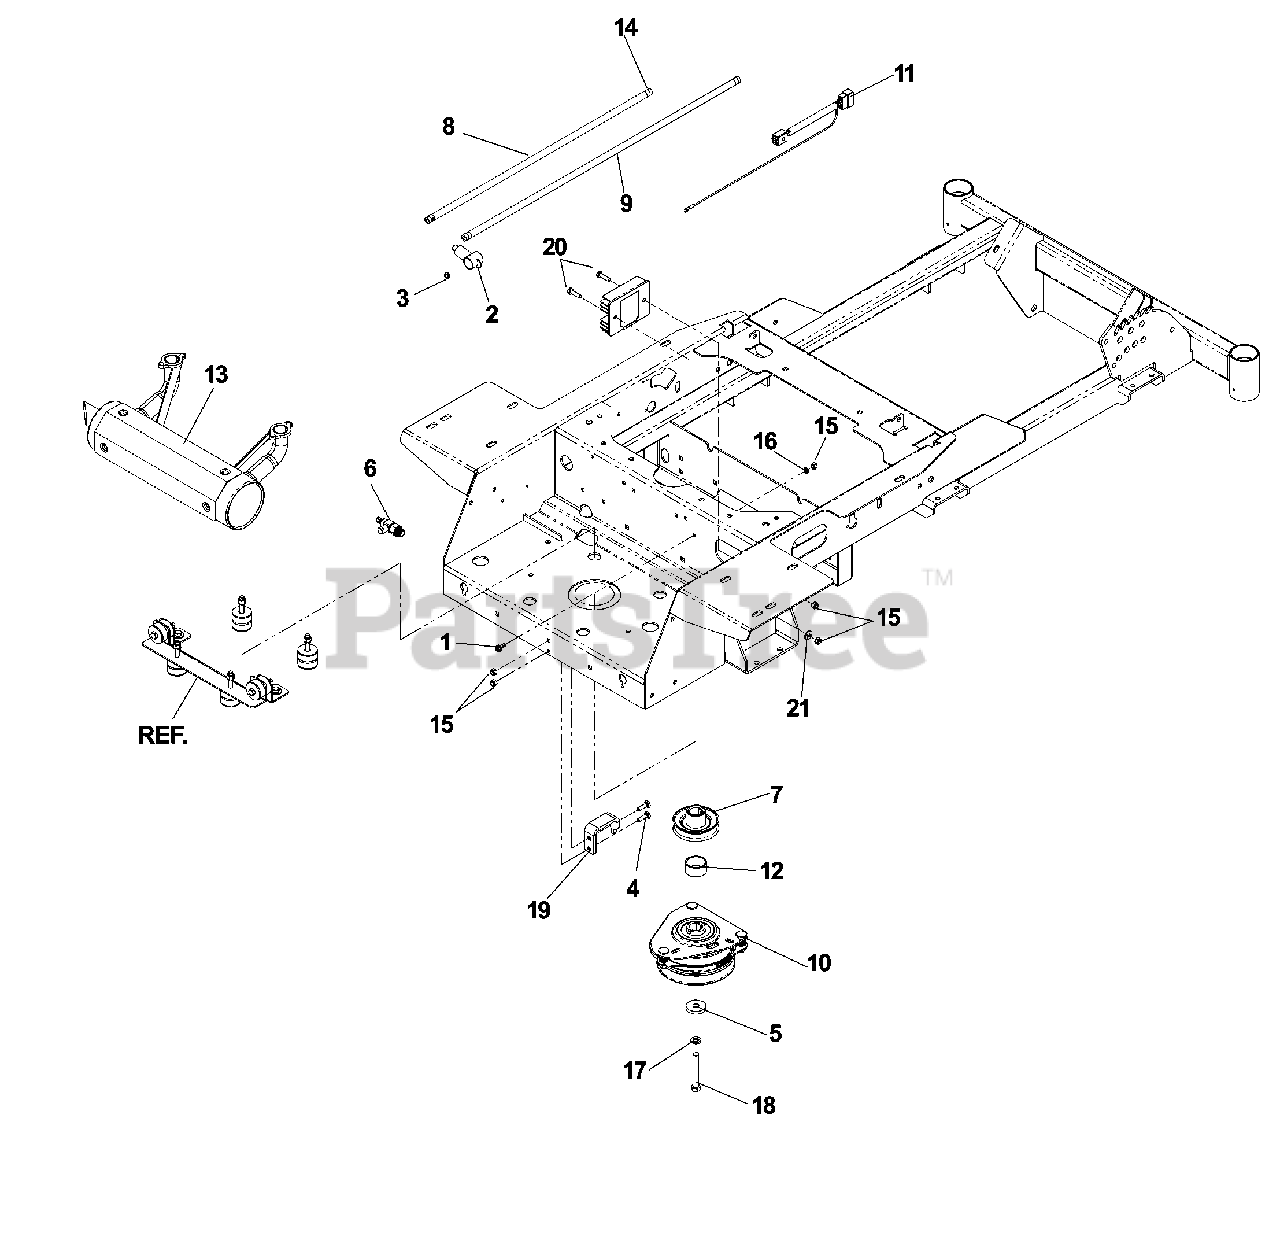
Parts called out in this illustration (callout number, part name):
1	SCREW- 1/4-20 X 5/8
2	INSULATOR
3	JAM NUT 1/4C
4	RHSNB, 1/4-20 X 1, GR5
5	CLUTCH, WASHER
6	OIL DRAIN ADAP.(HONDA)
7	PULLEY, ENGINE
8	FUEL LINE 24"
9	FUEL LINE 29.5"
10	CLUTCH, OGURA - 90 FT/LB
11	PIGTAIL, HONDA
12	SPACER, ENGINE - PULLEY
13	MUFFLER HONDA
14	HOSE CLAMP
15	NUT 1/4-20 NYLOC
16	WASHER 1/4 INT TOOTH
17	WASHER 7/16 LOCK
18	HEX SCREW 7/16-20 X 3
19	TIE DOWN, CLUTCH
20	HCS 1/4 X 1
21	WASHER 1/4 FLAT
